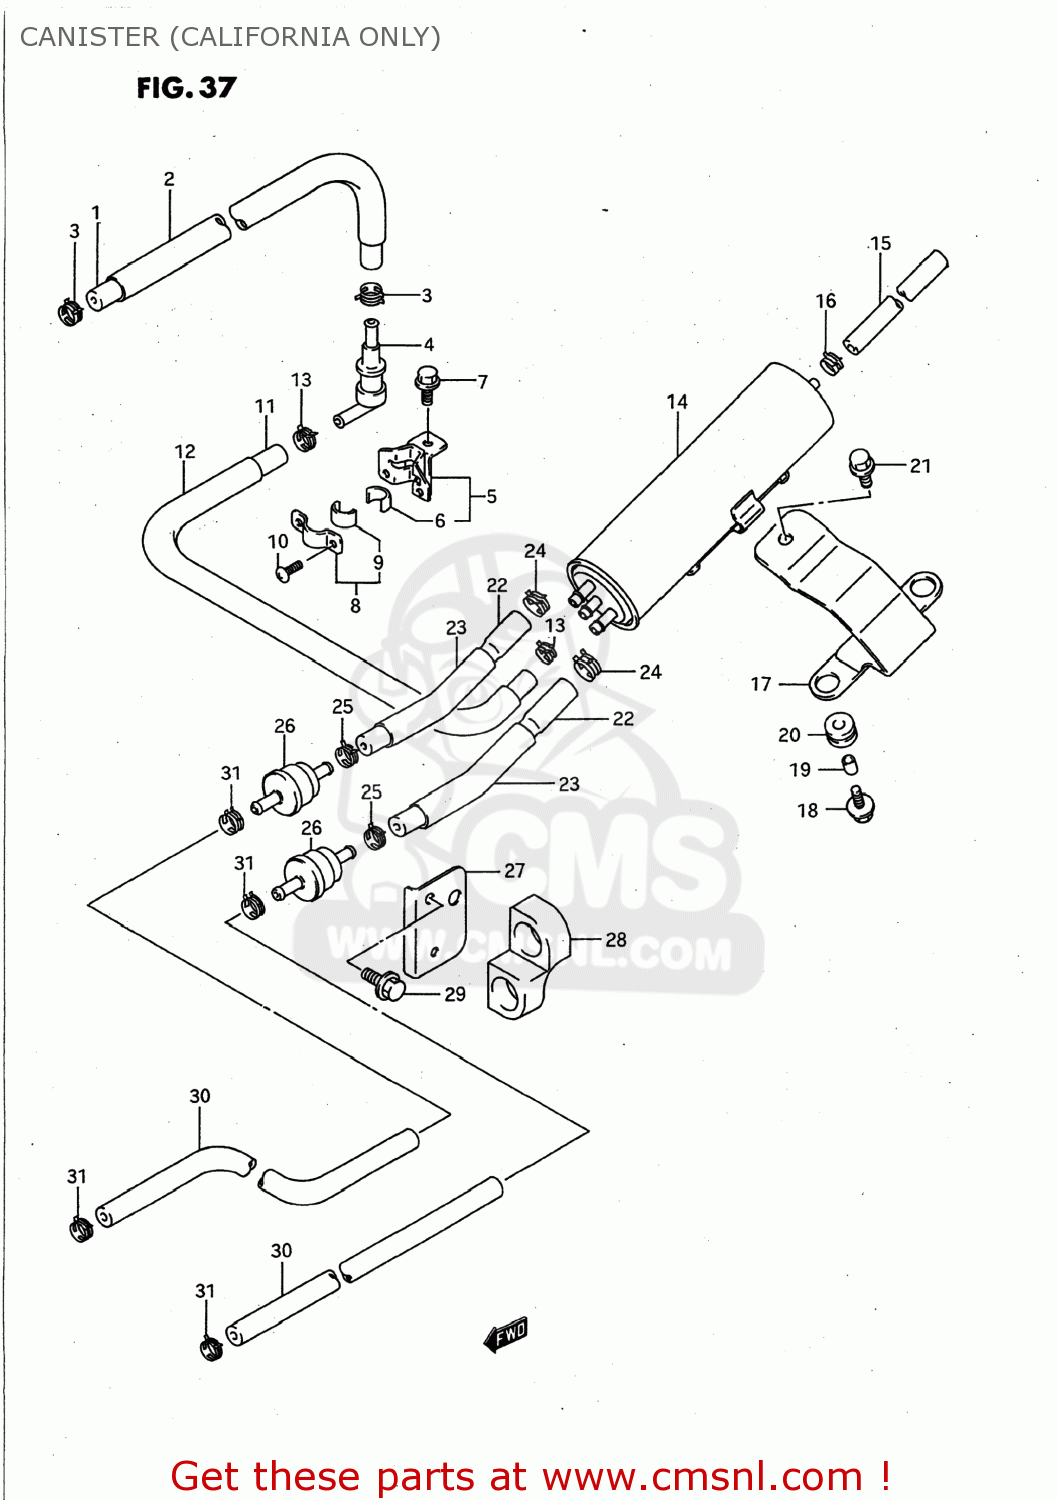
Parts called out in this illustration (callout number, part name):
1	HOSE (5.4X11.4X600)
2	PROTECTOR,FUEL HOSE
3	CLIP
4	VALVE,FUEL TANK BREATHER
5	BRACKET,BREATHER VALVE
6	CUSHION
7	BOLT
8	PLATE,FUEL TANK BREATHER NO.2
9	CUSHION
10	SCREW
11	HOSE (5.4X11.4X600)
12	PROTECTOR,EVAPORATOR HOSE,LEFT
13	CLIP
14	CANISTER ASSEMBLY,CHARCOAL
15	HOSE (7X12X150)
16	CLAMP
17	BRACKET,CANISTER
18	BOLT
19	SPACER
20	CUSHION
21	BOLT
22	HOSE(5.4X11.4X600)
23	PROTECTOR,EVAPORATOR HOSE,N
24	CLIP
25	CLIP
26	VALVE,CANISTER PURGE
27	BRACKET,CANISTER PURGE VALVE
28	(CA) CUSHION,CANISTER P VA
29	BOLT
30	HOSE (5.4X11.4X600)
31	CLIP
